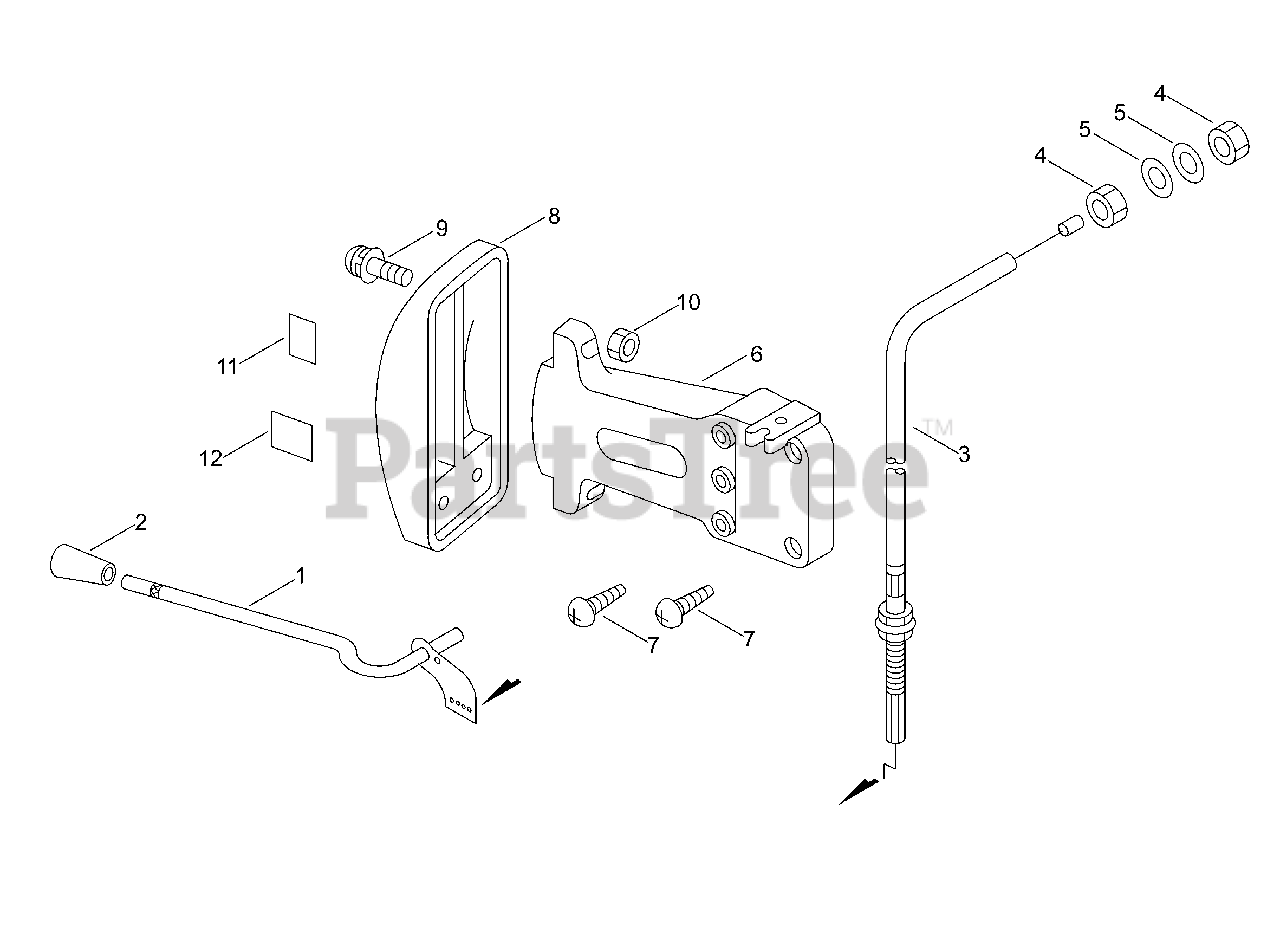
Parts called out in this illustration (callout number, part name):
1	LEVER, THROTTLE
2	KNOB, THROTTLE CONTROL
3	CABLE, THROTTLE
4	NUT 6 MM
5	WASHER 6.5×11.5×0.8
6	BRACKET, DIAL
7	SCREW 5×25 SUS
8	DIAL, METERING
9	SCREW 5×25 SUS
11	LABEL, THROTTLE
12	LABEL, ON-OFF
